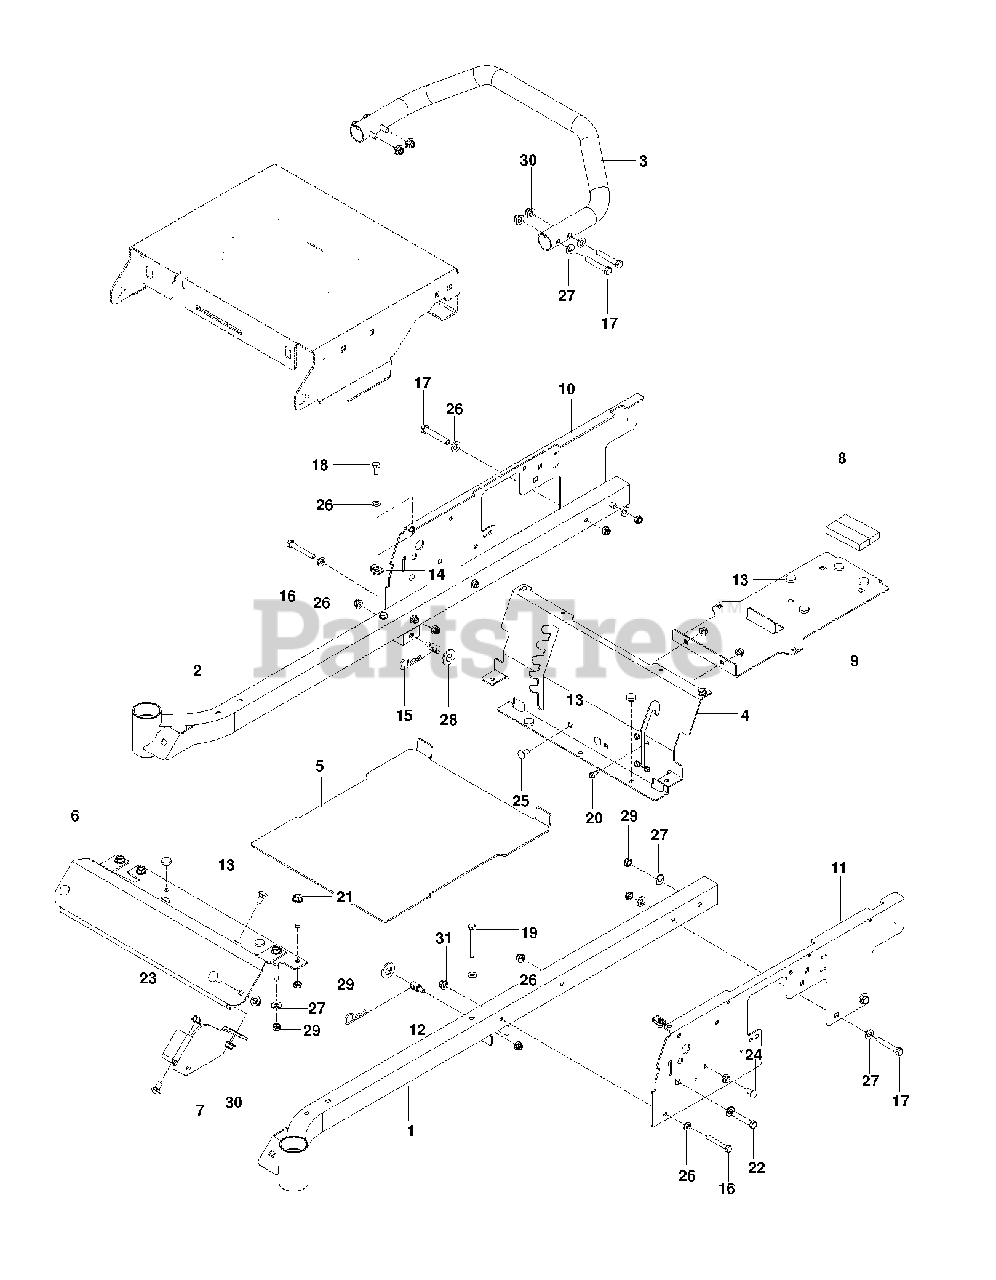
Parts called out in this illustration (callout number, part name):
1	FRAME, TUBE, LH, BLUE
2	FRAME TUBE, RH, BLUE
3	IMPACT BAR, BLUE
4	PANEL, SEAT SUPP. BLUE
6	FOOT REST, NAR. BLUE
7	BRACKET, FRONT DECK, BLK
8	FOAM STRIP, FUEL TANK
9	SUPPORT, TANK/BATT, BLK
10	PLATE, RH SIDE, BLUE
11	PLATE, LH SIDE, BLUE
12	STUD.FASTNER.W/ANTI-ROTATE
13	GROMMET, BUMPER
14	U-CLIP 5/16-18 NUT RETAINER
15	HAIRPIN #4
16	CAPSCREW
17	HCS 3/8C X 2 1/4
18	HCS 5/16C X 3/4
19	HCS 5/16C X 2-3/4
20	SCREW 1/4 X 5/8
21	ENGINE BOLT, SPECIAL
22	HCS 1/2C X 2 3/4
23	RHSNB 3/8C X 1
24	RHSNB 3/8-16 X 3/4 GR5 ZD
25	BOLT 5/16C X 3/4" CARRIAGE
26	FLAT WASHER 5/16 SAE
27	WASHER 3/8 SAE FLAT
28	WASHER 5/8 FLAT
29	NUT HEX 3/8-16 NYLON, THIN
30	NUT 3/8-16 HEX FLG NYLOC ZD
31	5/16-18 NYLOC FLANGE NUT
